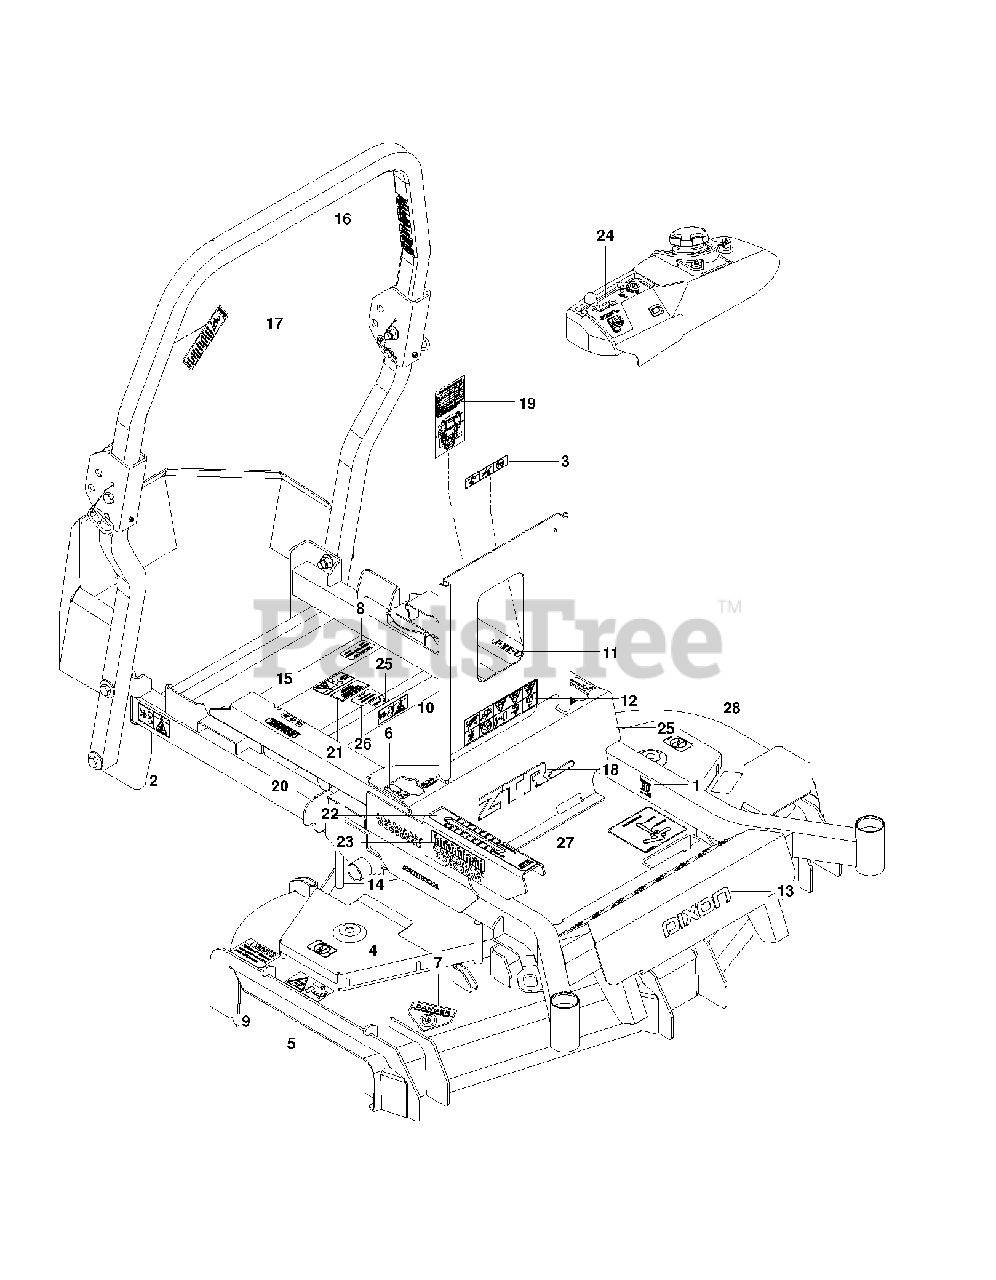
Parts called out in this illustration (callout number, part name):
1	DECAL, 72" BELT ROUTING
2	DECAL, BELT DRIVE
4	DECAL, NO STEP
5	DECAL, EURO SEVERING
6	DECAL, MOTION CONTROL
7	DECAL, CPSC
8	DECAL, PROP. 65
9	DECAL, CAUTION
10	DECAL, TRACKING
11	DECAL, PARK BRAKE
12	DECAL, WARNING
14	DECAL, COMMERCIAL
16	DECAL, ROPS
17	DECAL, ROPS, WARNING
19	DECAL, SERVICE
20	DECAL, WARNING SPARK ARRESTOR
22	DECAL, HEIGHT
23	DECAL, HEIGHT
25	DECAL, ECM, AUSTRALIA
26	DECAL, OIL TANK
27	DECAL, BELT ROUTING
